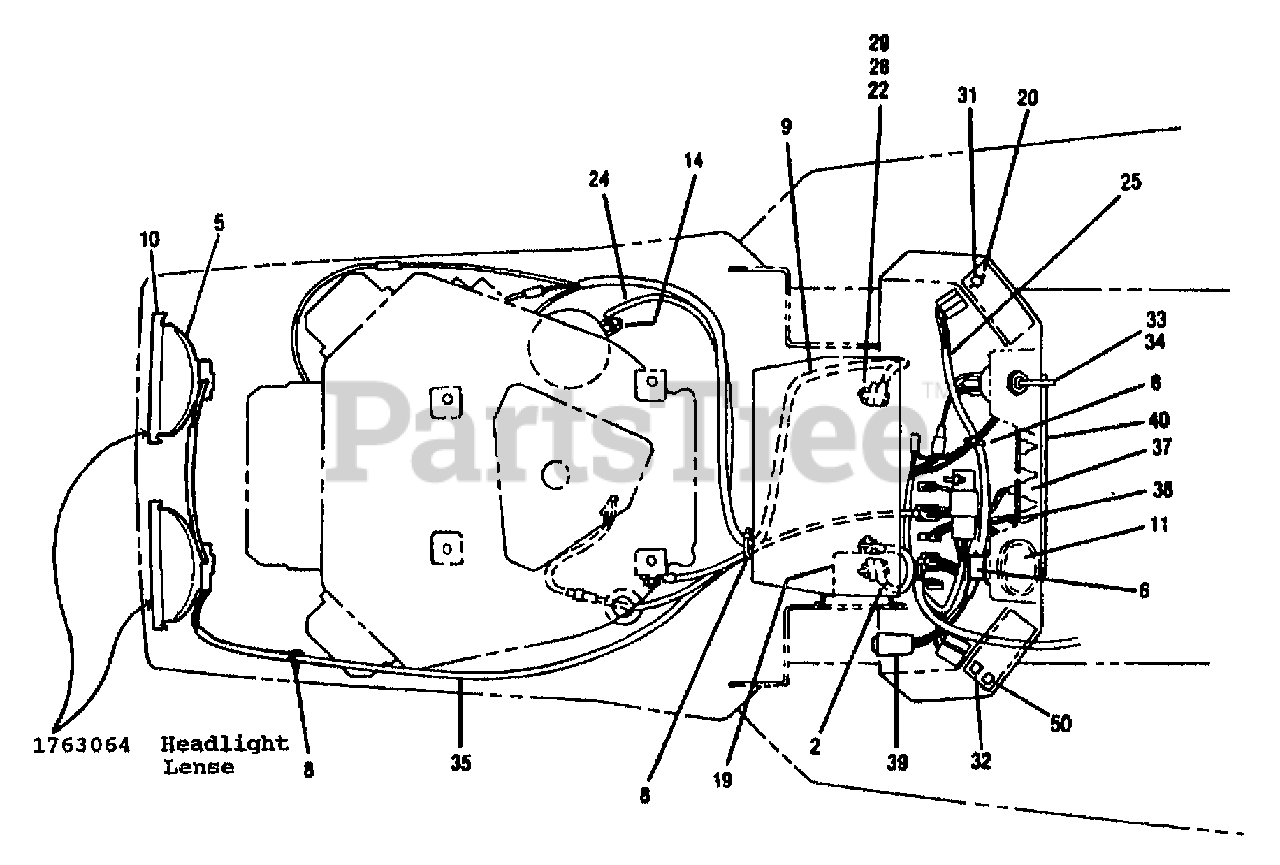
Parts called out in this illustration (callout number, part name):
2	CABLE-BATTERY (+)
5	ASSM-LIGHT
6	RELAY-SPEED CONTROL
8	TIE-CABLE NYLON BLACK
9	CABLE (-)
10	REFLECTOR
11	METER-HOUR
14	NUT-HT LK 1/4-20
19	SOLENOID
20	SCR-FHP #6-32X.50 ZP
22	NUT-HEX 1/4-20 ZP
24	CABLE-BATTERY (+)
25	HARNESS-CONSOLE WIRING
28	WASHER-LK .25 ZP
29	SCR-HH 1/4-20X.625 G5 ZP
31	SWITCH-PTO
32	SWITCH-LIGHT
33	SWITCH-IGNITION
34	KEY-IGNITION
35	HARNESS-ENGINE
37	BULB (MFG NO. GE 73)
38	SCR-PHP M6-32X.38 ZP
39	FUSE-30 AMP
40	LENSE
50	SWITCH-SPEED CONTROL
